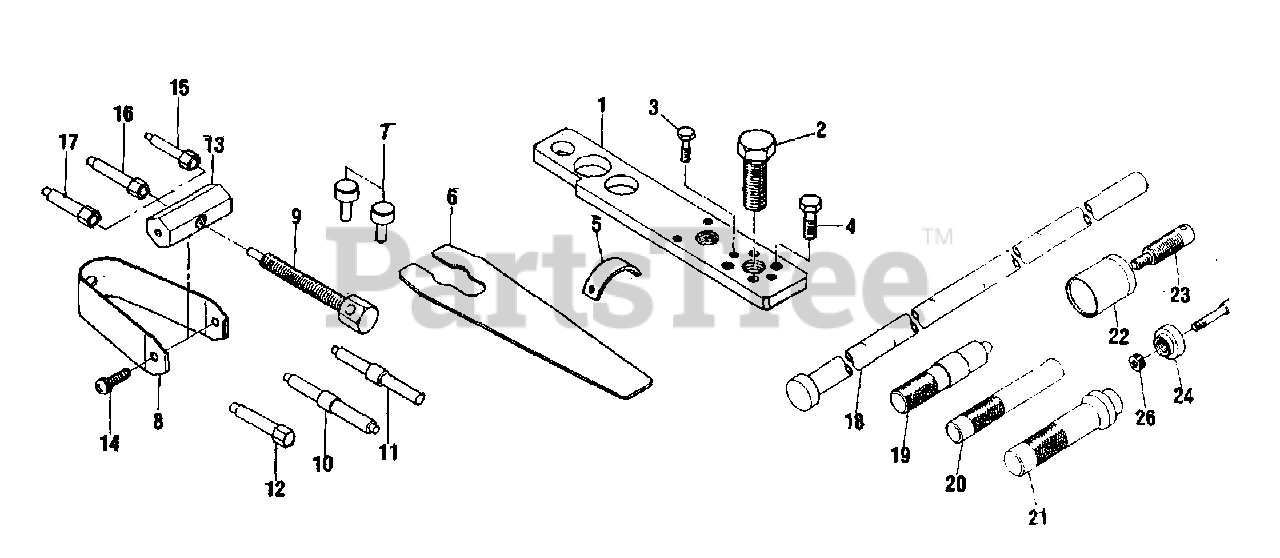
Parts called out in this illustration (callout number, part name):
2	BOLT, CENTER
3	BOLT
4	BOLT
5	GAUGE, GAP
6	SPANNER WRENCH, FLYWHEEL
7	STOPPER
9	BOLT
10	PING, GUIDE
11	PING, GUIDE
12	PING, GUIDE
13	BOSS
15	PIN, ADAPTOR
16	PIN, ADAPTOR
17	PIN, ADAPTOR
18	BUSHING DRIVER
19	BEARING DRIVER (6000 DDU)
20	BEARING DRIVER (6001 ZZ)
21	BEARING DRIVER (6202)
22	HOLDER
23	PULLER BOLT
24	HOLDER
25	PULLER BOLT
